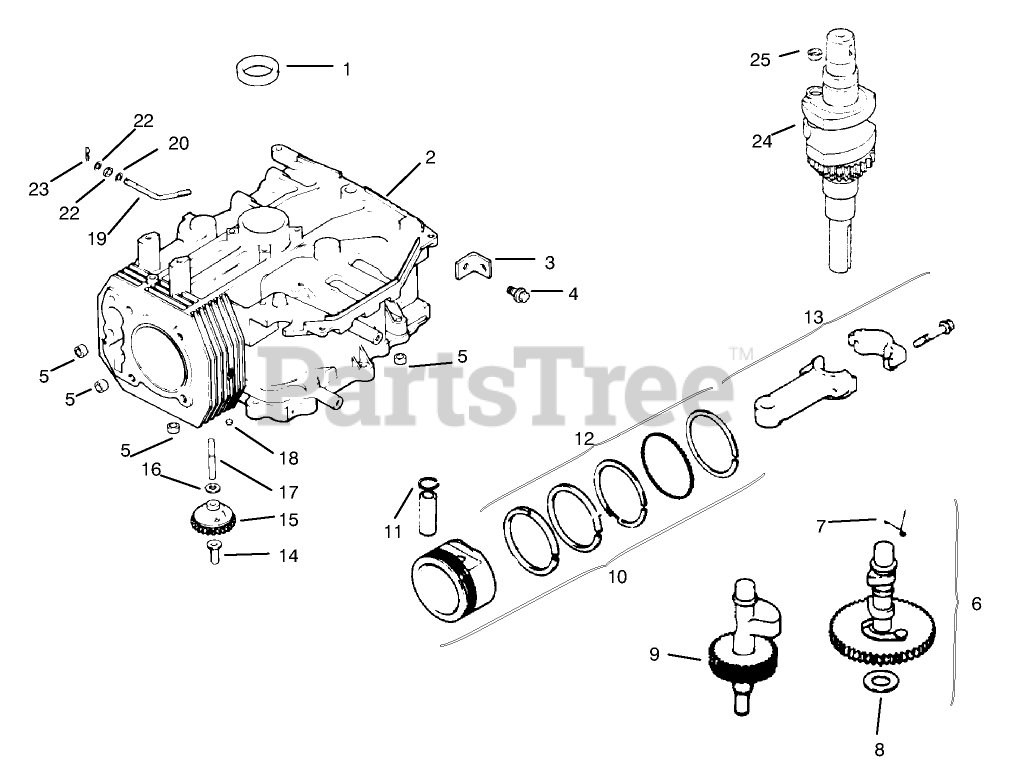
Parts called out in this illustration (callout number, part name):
1	Seal-Crankshaft
2	Short Block
3	Strap-Lifting
4	Screw
5	Pin-Dowel
6	Camshaft Assembly
7	Spring-Actuating
8	Shim-Camshaft
9	Shaft Balance
10	Set Piston w/Ring STD
10	Set-Piston w/Ring .25
10	Set-Piston w/Ring .50
11	Retainer-Piston Pin
12	Ring Set STD
12	Ring Set .25
12	Ring Set .50
13	Rod Connecting STD
13	Rod Connecting .25
14	Pin-Governor
15	Gear, governor
16	Washer
17	Shaft-Gear, Governor
18	Plug
19	Shaft-Governor Cross
20	Washer
21	Seal-Cross Shaft
22	Washer
23	Pin-Hitch
24	Crankshaft ASM
25	Plug-Cup
